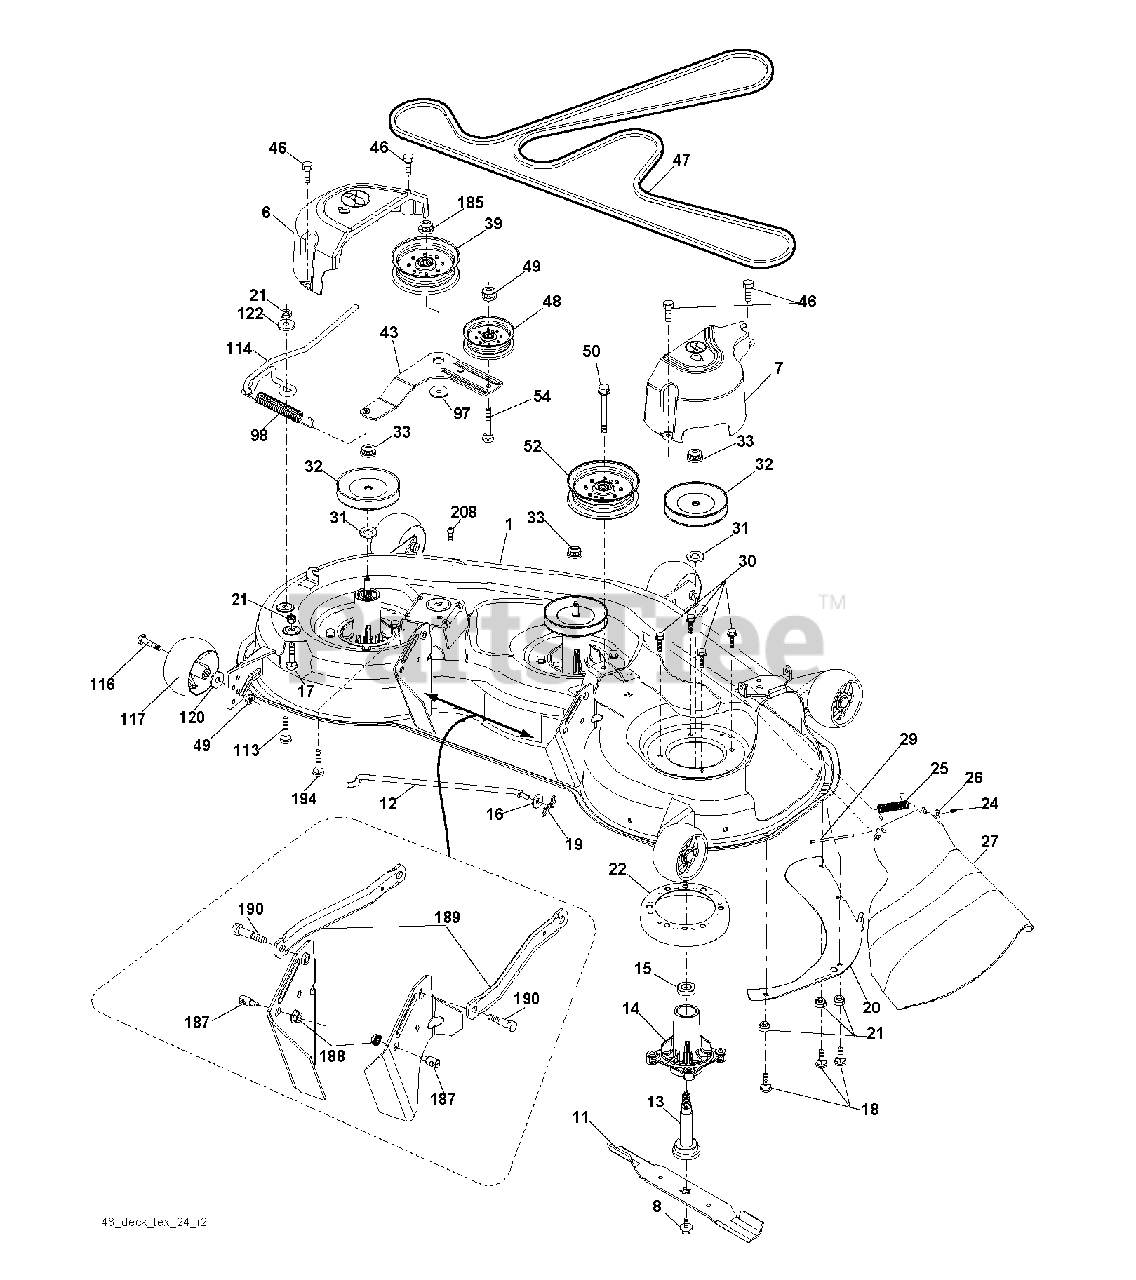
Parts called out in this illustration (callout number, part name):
1	DECK.WELDMENT.48"2006
6	COVER.MANDREL.LH.48"
7	COVER.MANDREL.RH.48"
8	BOLT 7/16 ASM BLADE
11	48" HI-LIFT BLADE
12	ROD.ANTI.SWAY.48/54"TE
13	SHAFT ASM MANDREL
14	HOUSING MANDREL
16	WASHER
17	BOLT
18	BOLT
19	PIN.COTTER.5/16.BOW TI
20	BAFFLE, VORTEX MWR
21	LOCKNUT
22	STRIPPER, MWR ROUND
24	CAP-SLEEVE LT
25	SPRING, TORSION
26	NUT PUSH M
27	DEFLECTOR SUBS TO 532 180655
29	ROD.HINGE
30	SCREW, WASHER HEAD
31	WASHER.SPACER.MANDREL
32	PULLEY MANDREL
33	NUT.FLANGE.LOCK.TOP
39	PULLEY.IDLER.4.50/HUB SPECIAL
43	ARM.IDLER
46	SCREW.1/4-20X5/8
47	BELT.DRIVE.DECK
48	PULLEY.IDLER.48"PRIMARY
49	NUT LOCK FLG 3/8-16 UNC
50	SCREW TT 3/8-16X2-1/4 UNC
52	PULLEY.IDLER.2006
54	BOLT.3/8-16X1.50
98	SPRING, DECK DRIVE
114	ROD.TENSION.RELIEF.TEX
116	BOLT.SHOULDER.3/8-16X3-5/8
117	WHEEL. GUAGE RALLY
122	BUSHING.RELIEF.TENSION
185	NUT.LOCK.FLANGE.7/16
187	STUD.FASTNER.W/ANTI-ROTATE
188	NUT LOCK HEX FLANGE 5/16-18
189	ARM.SUSPENSION.MOWER
190	BOLT.SHOULDER
194	BOLT.CARR.SQNK.7/16
